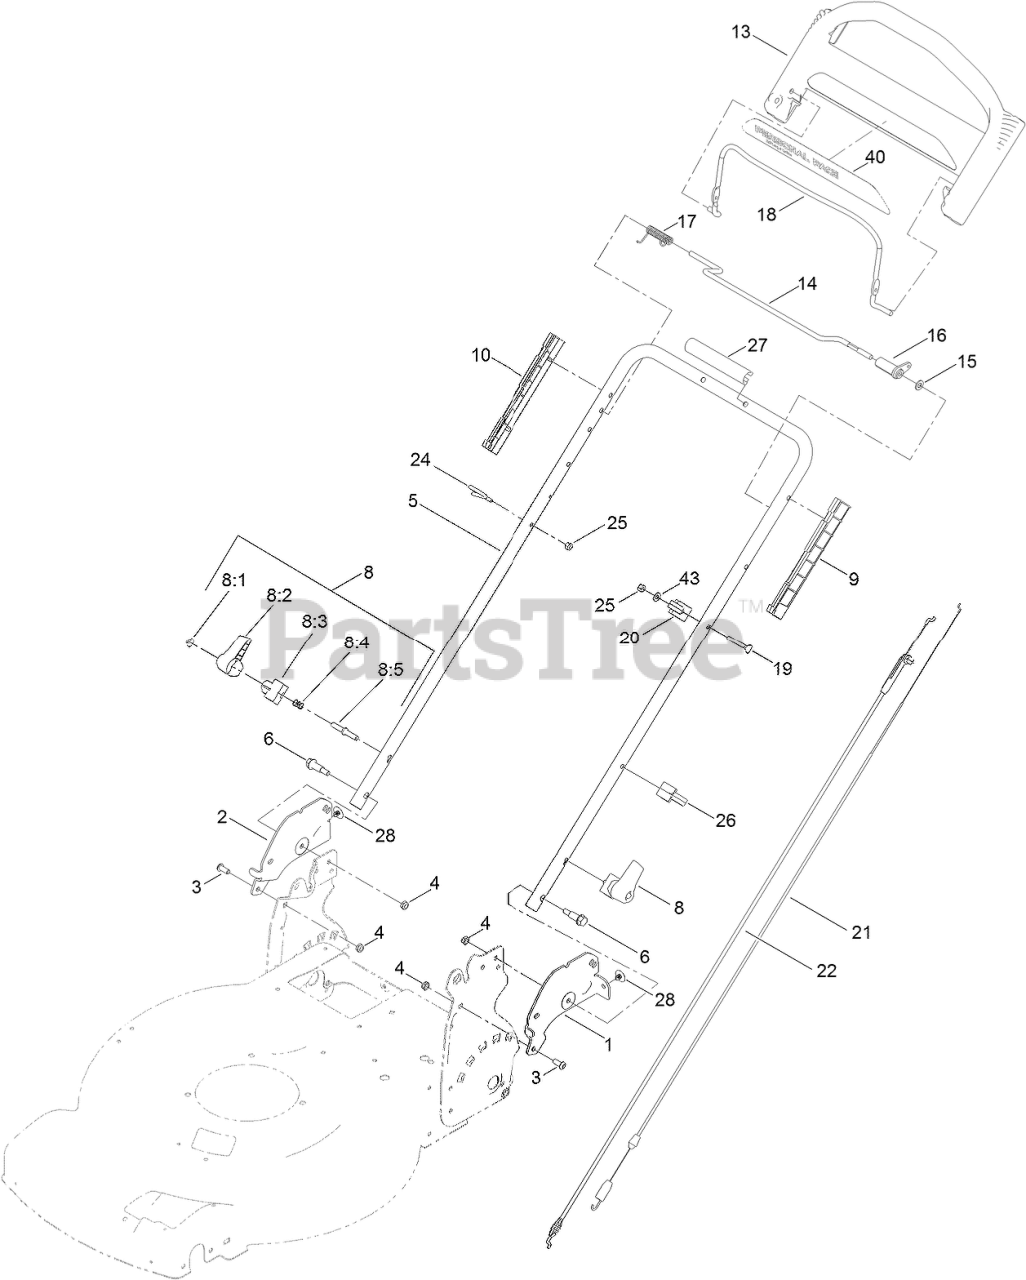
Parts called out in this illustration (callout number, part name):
1	PLATE-HANDLE, LH
2	PLATE-HANDLE, RH
3	SCREW-HSBH
4	NUT-LOCK, NI
6	BOLT-SHOULDER
8	QUICK RELEASE ASM
8:1	NUT-PUSH
8:2	LEVER
8:3	ANCHOR-SPRING
8:4	SPRING-COMPRESSION
8:5	ROD-RELEASE
9	GUIDE-LH
10	GUIDE-RH
13	HANDLE-CONTROL
14	BAR-CONTROL, TRACTION
15	WASHER-PLAIN
16	LEVER-TRACTION
18	BAIL-BRAKE
19	SCREW
20	ANCHOR-CABLE
21	CABLE-TRACTION
22	CABLE-BRAKE
24	GUIDE-ROPE
25	NUT-LOCK, NI
26	GUIDE-CABLE
27	HANDLE-COVER
28	CLIP-TREE
43	WASHER-FLAT
